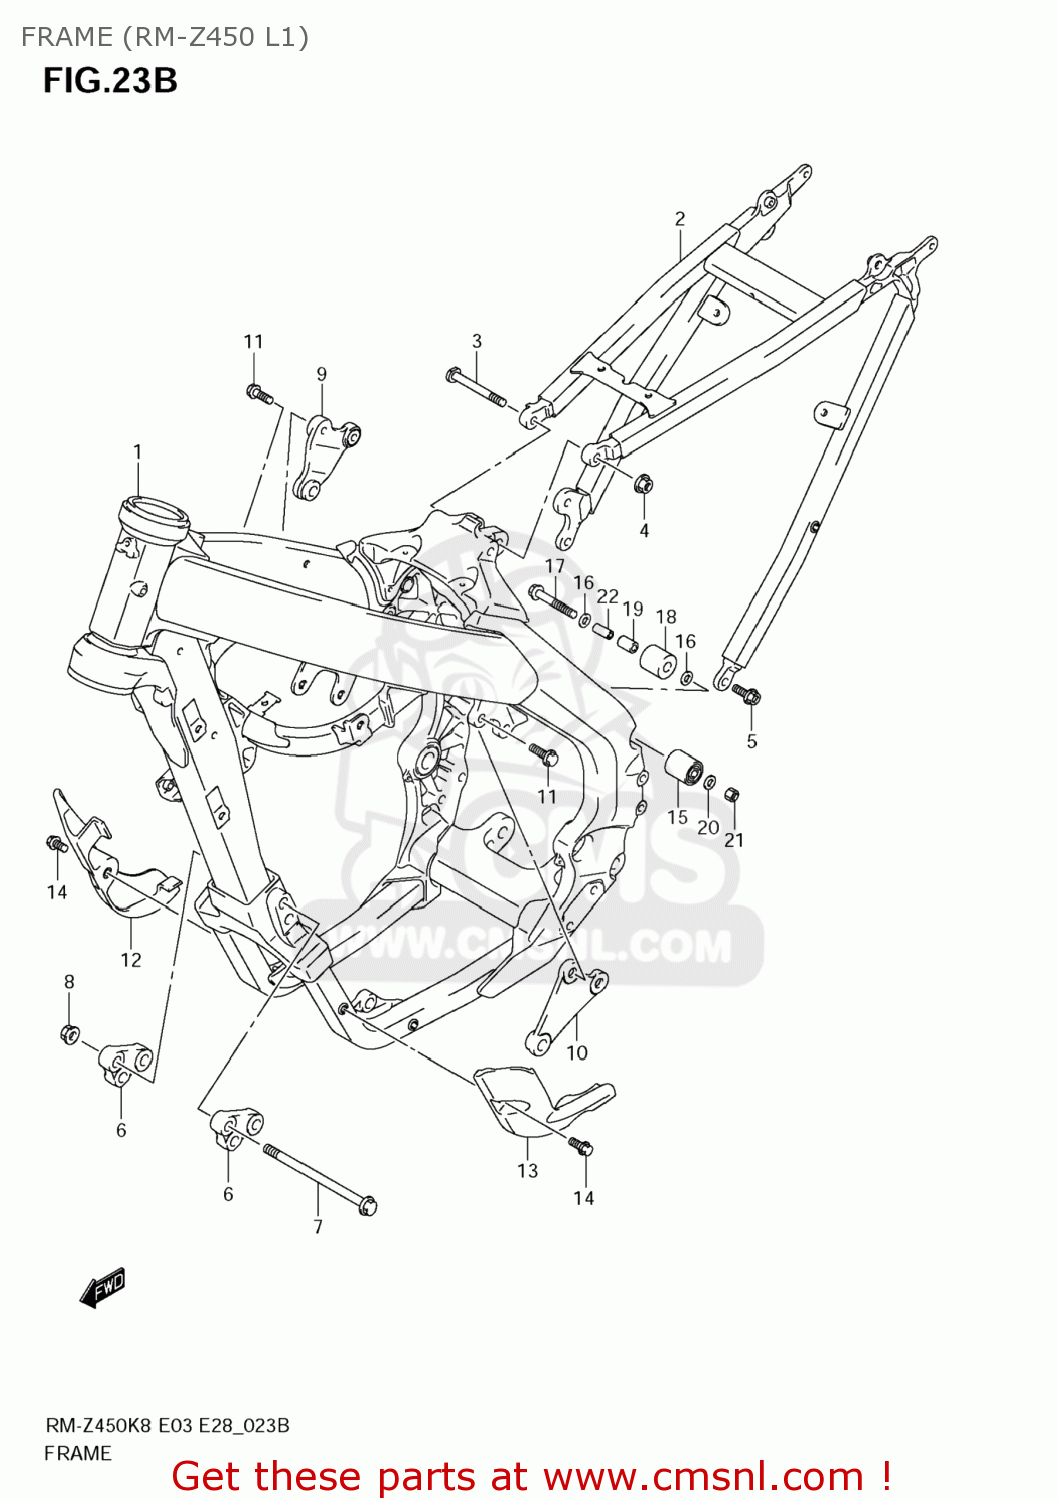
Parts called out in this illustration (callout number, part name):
1	FRAME
2	RAIL COMP,SEAT
3	BOLT,SEAT RAIL UPR
4	NUT
5	BOLT(8X23)
6	BRACKET,ENGINE MOUNTING FR
7	BOLT(10X135)
8	NUT
9	BRACKET,ENGINE MOUNTING UPR,R
10	STEUN
11	BOLT(8X21)
12	PROTECTOR,FR,R
13	PROTECTOR,FR,L
14	BOLT(6X25)
15	ROLLER,CHAIN
16	WASHER(8.5X23X1.5)
17	BOLT(8X45)
18	ROLLER,CHAIN
19	COLLAR,CHAIN ROLLER
20	SHIM(8X12X1)
21	NUT
22	SPACER(8.6X12.2X25.5)
